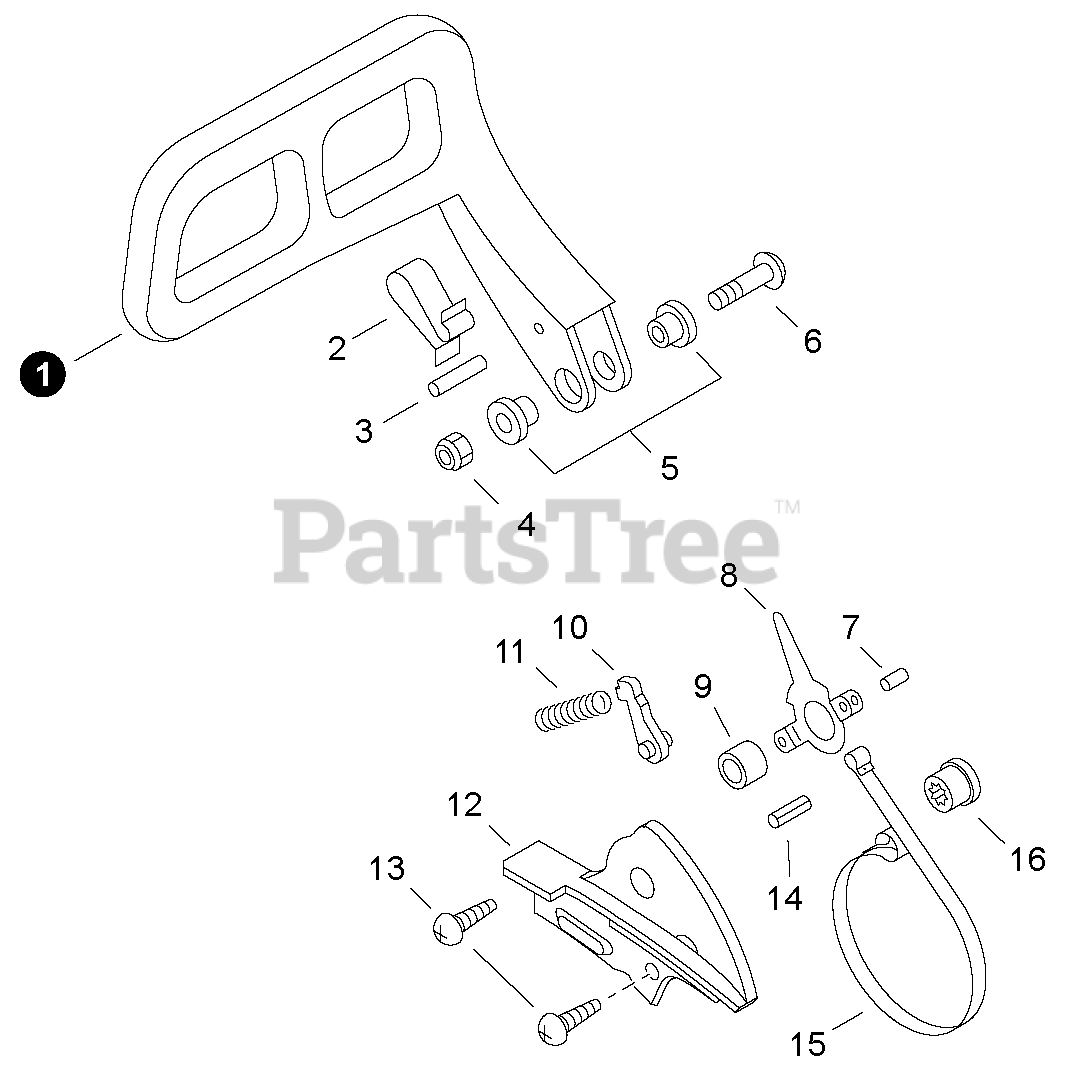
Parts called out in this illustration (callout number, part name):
1	LEVER, BRAKE
3	PIN - 3X24
4	LOCKNUT - 5
5	SPACER - 5
6	SCREW - 5X32
7	PIN - SPRING -- 4X8
8	LEVER, BRAKE
9	WASHER - 5
10	STOPPER, BRAKE
11	SPRING, BRAKE
12	COVER, BRAKE
13	SCREW - 4X10
14	PIN - SPRING -- 2.5X12
15	BAND, BRAKE
16	ADJUSTER, BRAKE BAND
